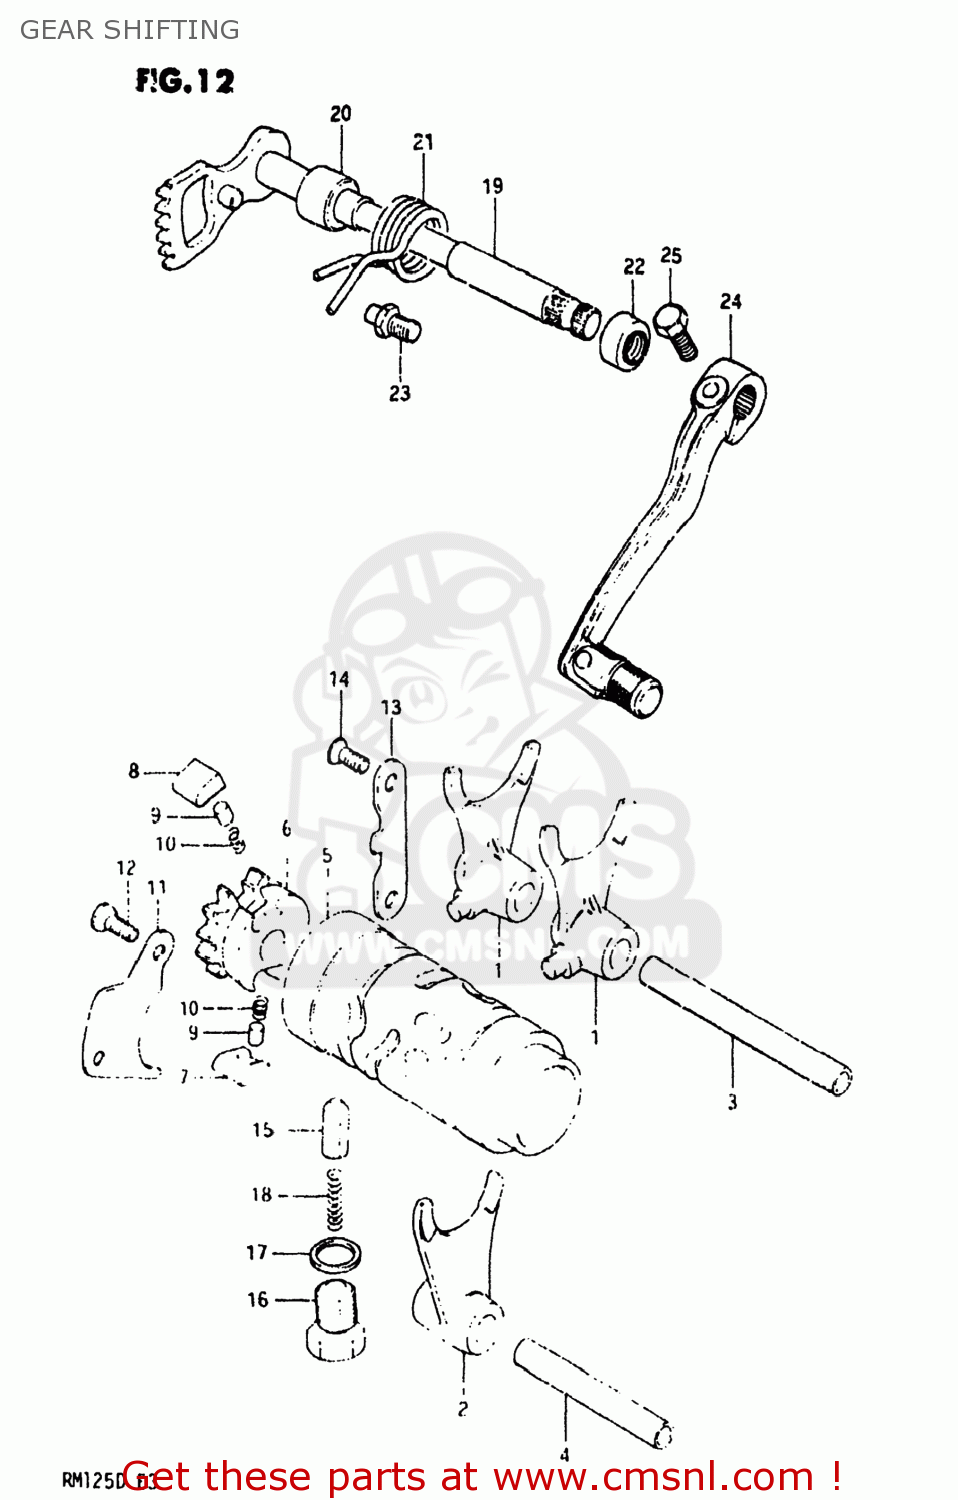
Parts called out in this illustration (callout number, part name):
1	FORK,GEAR SHIFT NO.1
2	FORK,GEAR SHIFT NO.2
3	SHAFT,GEAR SHIFT FORK
4	SHAFT,GEAR SHIFT FORK
5	CAM,GEAR SHIFT
6	RETAINER,GEAR SHIFT CAM
7	PAWL,GEAR SHIFT NO.1
8	PAWL,GEAR SHIFT NO.2
9	PIN(5X8)
10	SPRING
11	LIFTER,GEAR SHIFT PAWL
12	SCREW
13	STOPPER,GEAR SHIFT POLE
14	SCREW
15	STOPPER,GEAR SHIFTING
16	HOUSING,GEAR SHIFT CAM STOPPER
17	GASKET(14X19.2X2) (NAS)
18	SPRING
19	SHAFT,GEAR SHIFT
20	SPACER(12X20X15.3)
21	SPRING
22	OIL SEAL
23	STOPPER, ARM
24	LEVER ASSEMBLY,GEAR SHIFTING
25	BOLT
